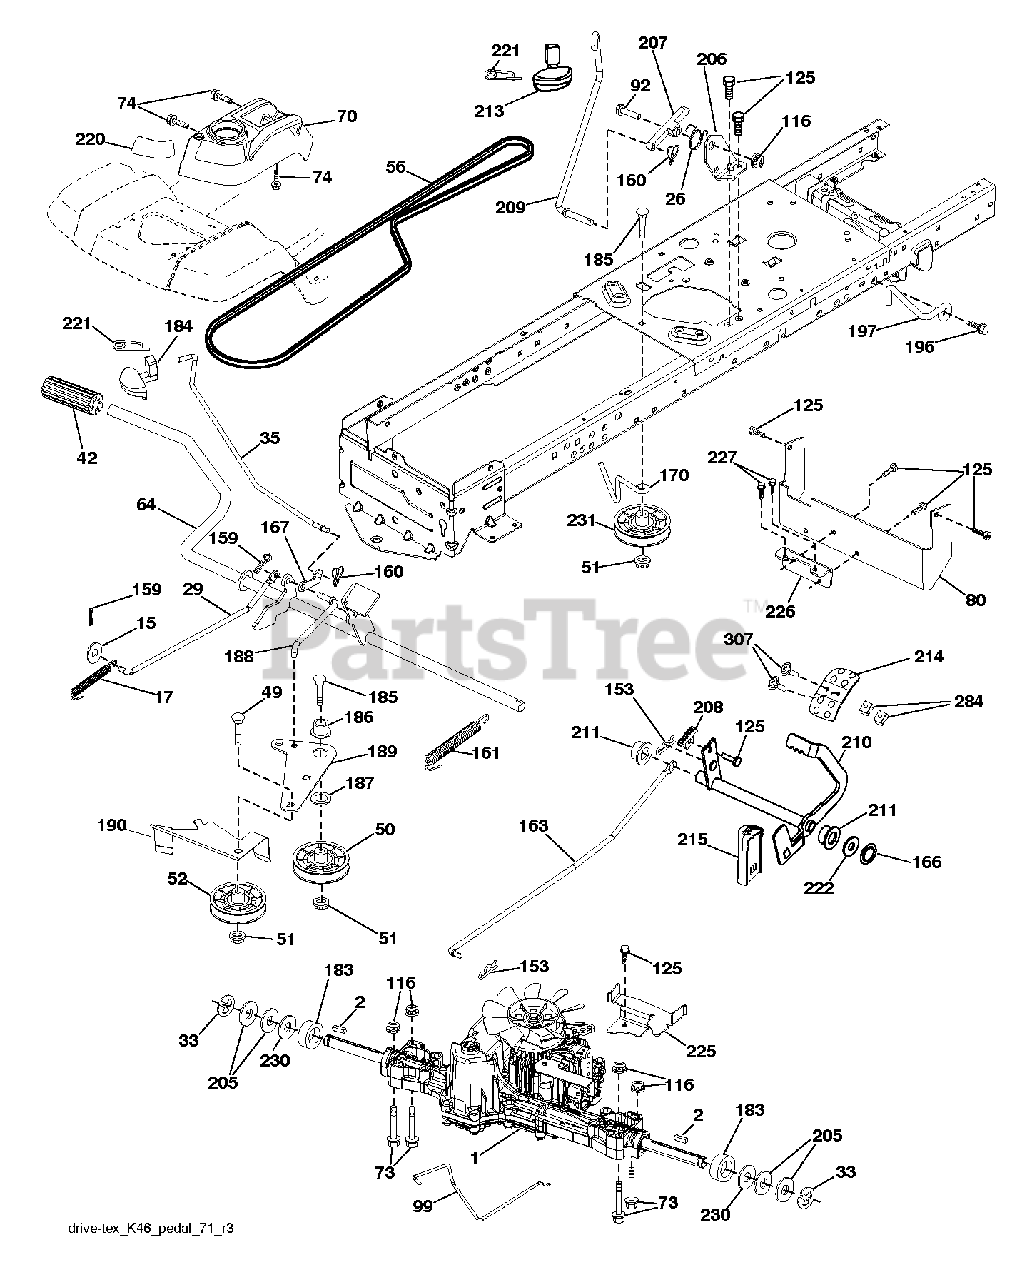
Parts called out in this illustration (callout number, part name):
2	SQUARE KEY
15	WASHER
17	SPRING.BRAKE.K46.GREEN
26	SPRING.RETURN.CRUISE
29	ROD.BRAKE.K46
35	ROD .BRAKE. PARKING. GT. HUSQ.
42	PEDAL COVER T
50	IDLER.FLAT.910.OFFSET
51	NUT LOCK FLG 3/8-16 UNC
52	IDLER.V-GROOVE.910.OFFSET
56	V-BELT.MOWER.92.40.42/K46
64	SHAFT.ASM.PEDAL.BRK.CNTR
70	CONSOLE.ASM.RH.GT.FC.HUSQ
73	BOLT HEX 5/16-18 GR 5
74	SCREW.HI-LO.CONSOLE
80	STRAP.TORQUE.K46.K57R.TT
92	BOLT
99	ROD.SPRING.BYPASS.K46.LT.Z
116	NUT LOCK HEX FLANGE 5/16-18
125	SCREW
153	RETAINER M
159	COTTER PIN
160	RETAINER CLIP
161	SPRING, RETURN LT
163	ROD.CONTROL.K57R.K46
166	NUT.PUSH.625
167	LATCH.BRAKE.SPRING
170	KEEPER.CENTER SPAN.1.688
183	SPACER AXLE
184	RB HANDLE.PARKG.BRK.HUS/PRED
186	SPACER.RETAINER
187	WASHER 12/32X2X10GA
188	RP LINK.CLUTCH.GROUND.DRIVE
189	BELLCRANK.GROUND.DRIVE.TEX.
190	KEEPER.BELLCRANK.DRIVE
196	SCREW 3/8-16X1
197	LINK.CLUTCH.ANIT-ROTAT
206	BRACKET.MOUNT.CRUISE.LATCH
207	LATCH.CONTROL.CRUISE
208	GEAR.SECTOR.CONTROL.CR
209	ROD.CONTROL.CRUISE.GT.
210	ROCKER.ASM.PEDAL.CONTR
211	BEARING.NYLON
213	KNOB.CONTROL.CRUSIE.HU
214	PEDAL.FORWARD.HUSQVARNA.DEALER
215	PEDAL.REVERSE.TEX.GT.4
220	REFLECTOR.RH.TEX GT
221	RETAINER.SPRING.CLIP.H
222	WASHER 21/32 X 1-1/4 X 10 GA.
225	KEEPER.BELT.TRANSAXLE.K46
226	BRACKET.MOUNT.TORQUE.K46.TLT
227	SCREW
230	WASHER.HARDENED
231	IDLER.V-GROOVE.1.688.OFFSET
284	NUT.U-CHNL.1/4-20.550DP.350PNL
307	SCREW.MACHINE.CR.1/4-20
